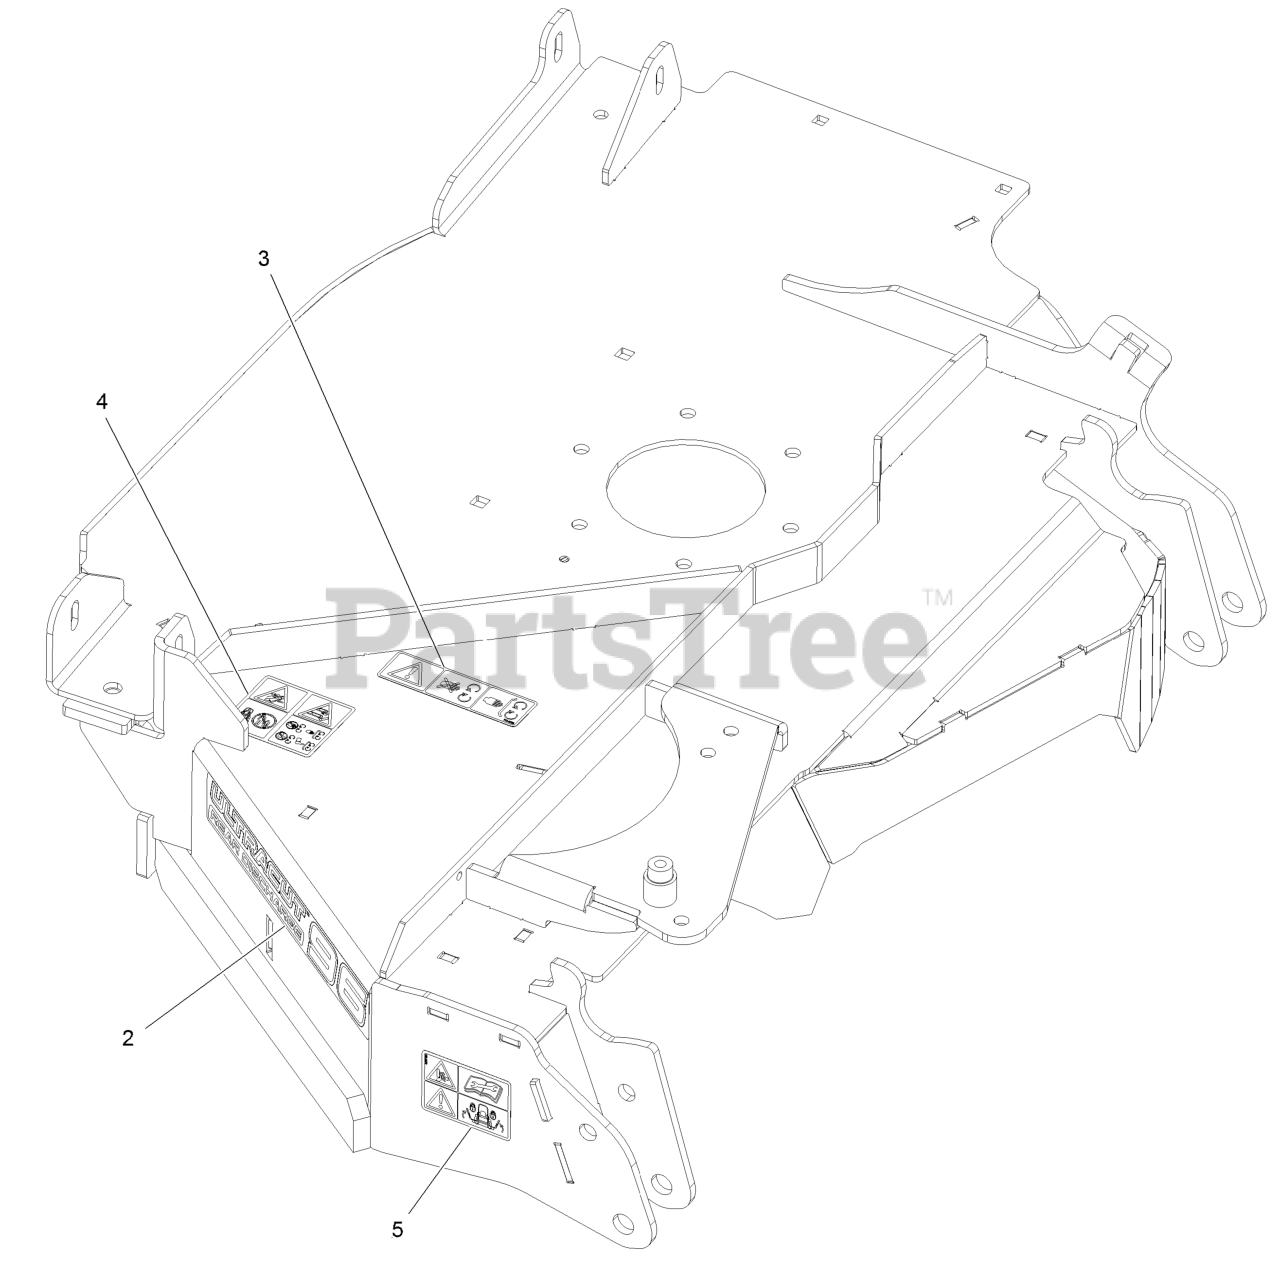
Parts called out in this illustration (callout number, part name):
2	Decal-Ultracut 96-Rd
3	Decal-Cover, Missing
4	Decal-Danger, Thrown Object
5	Decal-Warning, Pinch Point
